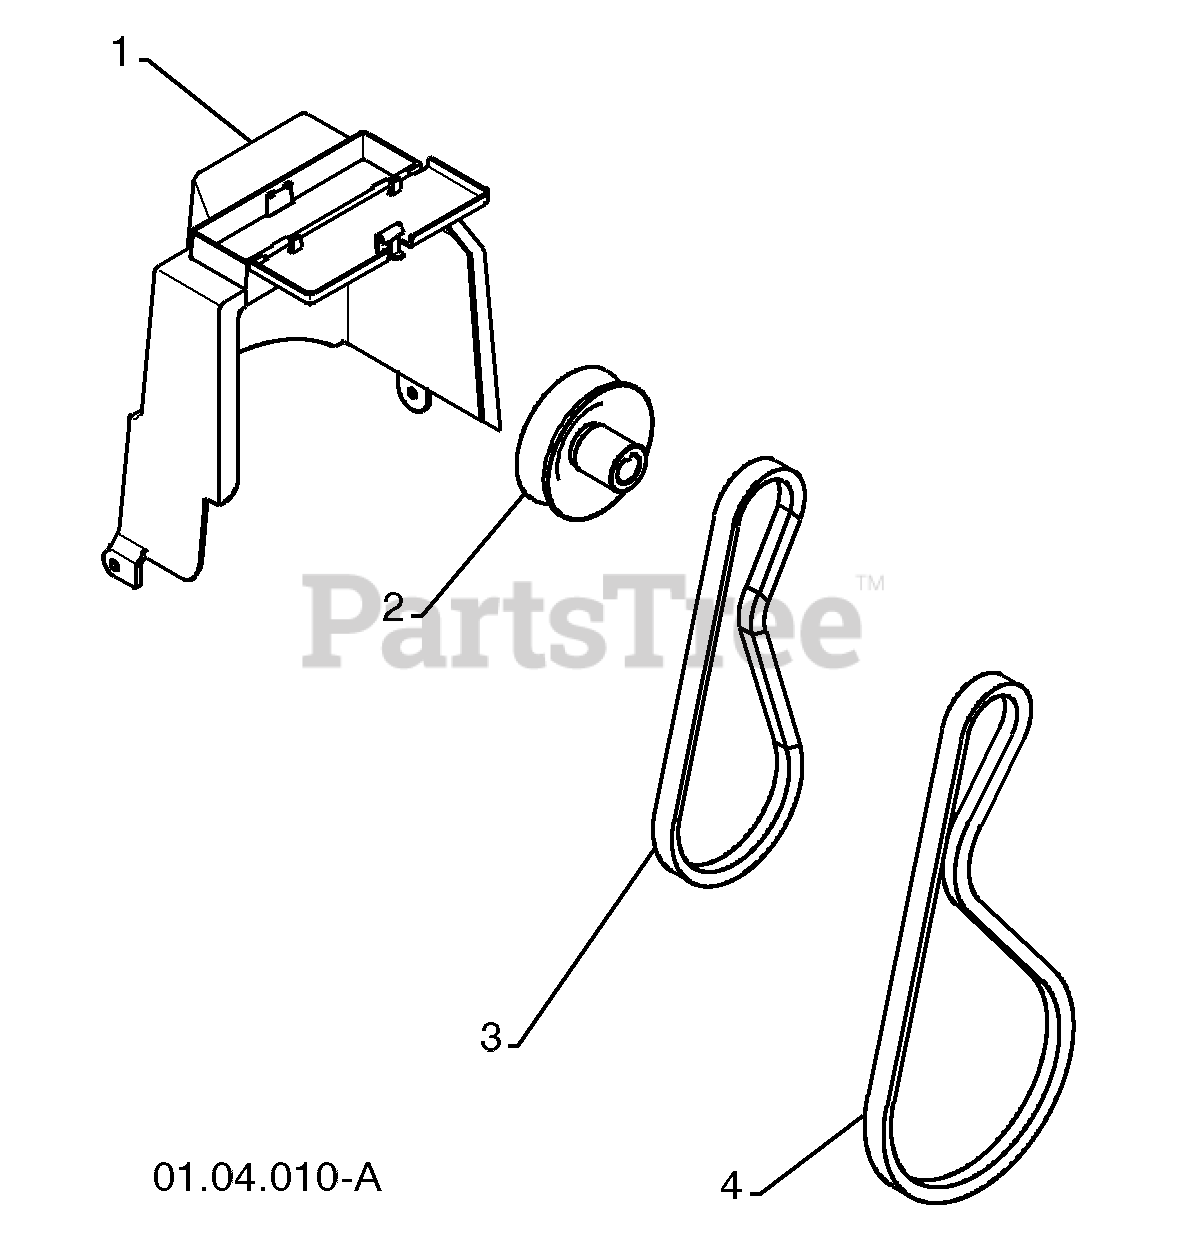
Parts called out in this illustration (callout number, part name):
1	COVER ASSEMBLY
2	PULLEY
3	TRACTION BELT
4	IMPELLER BELT
